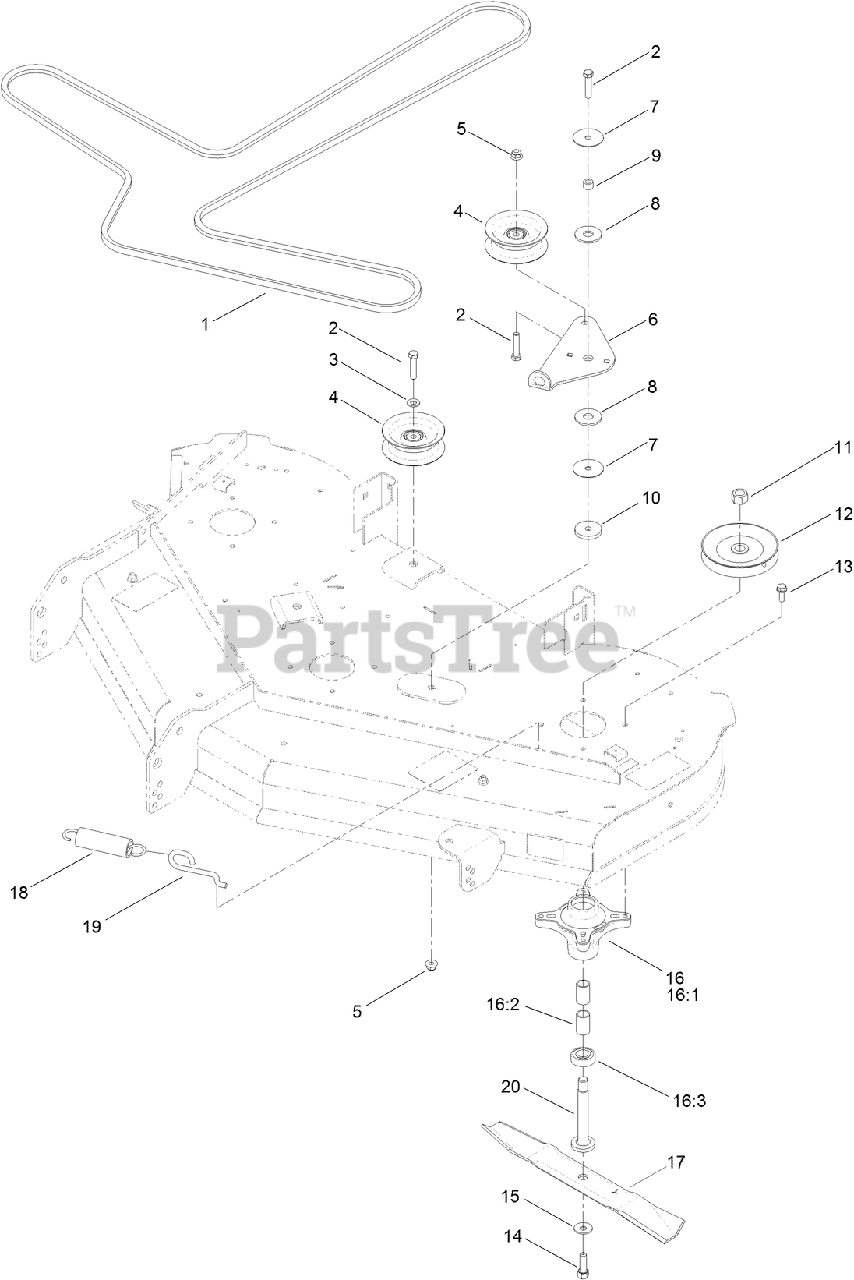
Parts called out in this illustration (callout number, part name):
1	V-BELT
2	SCREW-HH
3	WASHER-FLAT
5	NUT-HF, NI
6	ARM-IDLER
7	WASHER
8	WASHER-FRICTION, COMPOSITE
9	SPACER
10	WASHER-PLAIN
11	NUT-HEX
12	PULLEY
13	SCREW-TAPTITE
14	SCREW-HH
15	WASHER-BELLEVILLE
16	SPINDLE ASM
16:2	SPACER
17	BLADE-MULCH, 17.50 INCH
18	SPRING-EXTENSION
19	HOOK-RETURN, SPRING
20	SHAFT-SPINDLE
